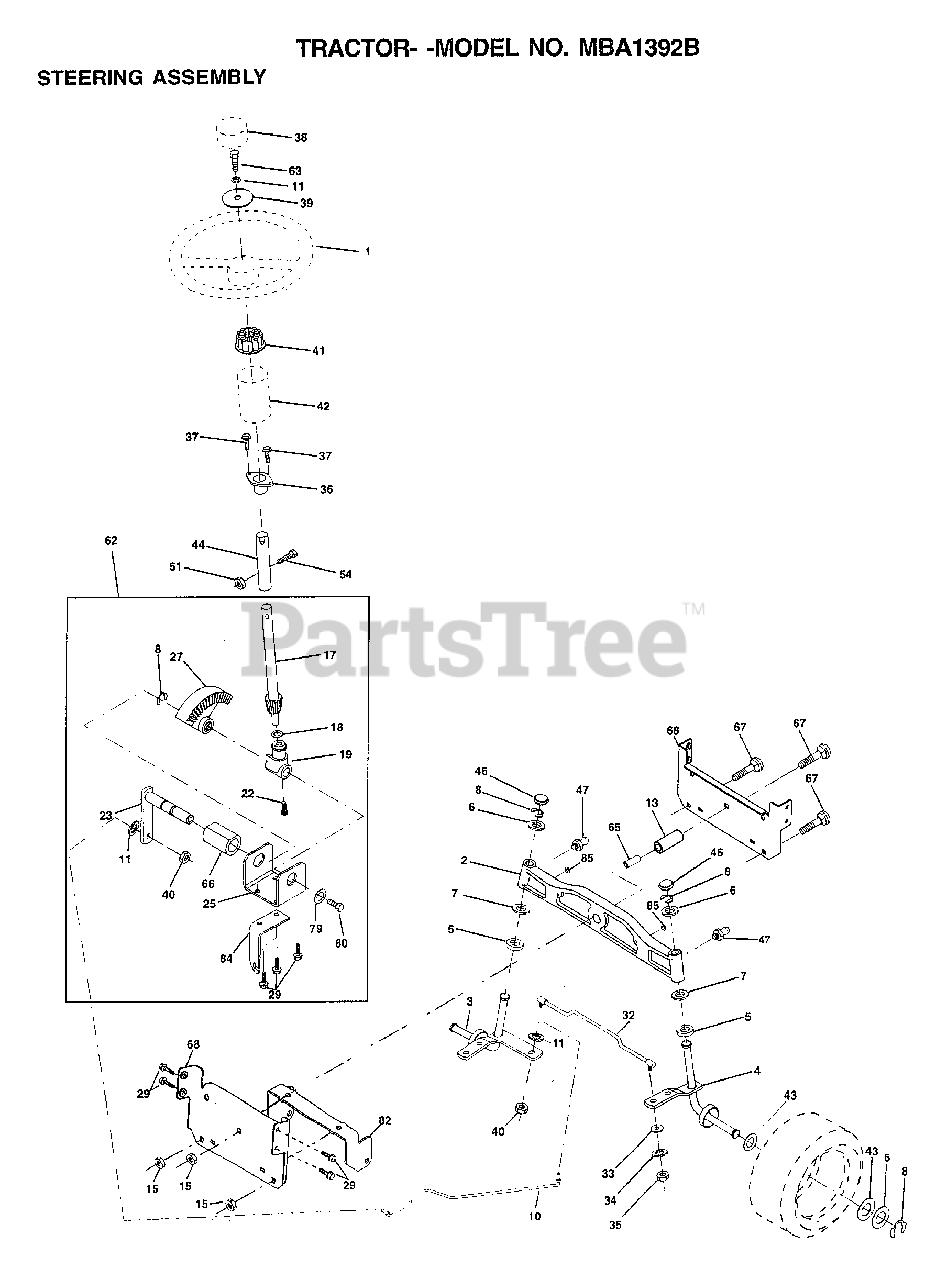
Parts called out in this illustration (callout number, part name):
2	AXLE ASM CAST IRON LT
3	SPINDLE ASM
4	SPINDLE ASM
5	WASHER .T
6	WASHER
7	WASHER
8	RING
10	LINK DRAG
11	LOCKWASHER
13	SPACER BEARING
15	NUT.HXFLG.LOCK.
17	SHAFT ASM STEERIN
18	THRUST WASHER
19	SUPPORT.SHAFT.STEER
22	SCREW.HX.WSH.HD
23	SHAFT.ASM.PITMAN
25	BRKT-STEERING
27	GEAR SECTOR
29	SCREW
32	TIE ROD
33	WASHER M
34	LOCKWASHER
35	NUT.LOCK.5/16-24
36	BUSHING.STEERING
37	"SCREW-TT,10-32 FL"
38	CAP WHEEL STEER
39	WASHER
40	GRIPCO NUT
41	ADAPTER LT
42	BOOT.STEERING.DASH.P/L
43	WASHER
44	EXT SHAFT STEERIN
46	CAP
47	ZERK M
51	NUT
54	BOLT
62	KIT.STEER.ASM
63	BOLT
65	"SPACER BRCAE,AXLE"
66	"BEARING-ARM,PITMA"
67	BOLT RDHD 3/8-16
68	BRACE AXLE
79	WASHER
80	BOLT.HX.NYLON3/8-16X3/
82	METER HOUR
84	BRACKET CABLE CLUTCH CHASSIS
85	XMAS TREE FASTNER
